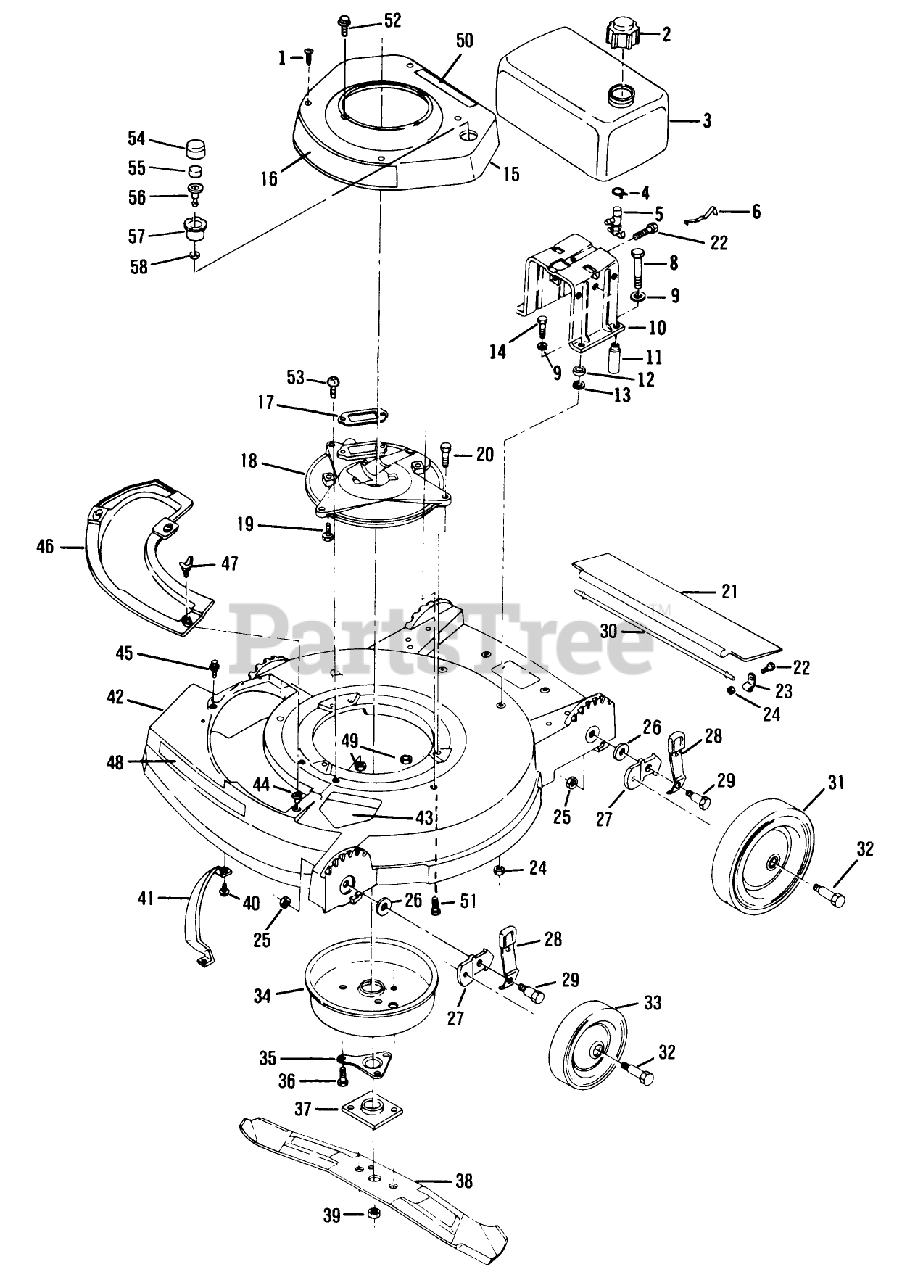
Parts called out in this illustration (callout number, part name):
1	SCREW - SELF TAPPING
2	FUEL CAP & INSERT
3	TANK - FUEL
4	CLAMP - HOSE S
5	VALVE&SCREEN SM
6	SPRING
9	WASHER
13	WASHER
14	BOLT PIONEER
18	PLATE F
19	SCREW V
20	SCREW-HH
21	T/SHIELD GEAUGA
23	CLAMP ROD KMC
24	LOCKNUT E
26	WASHER
29	BOLT
30	ROD 21" ADVANCE
31	WHEEL & TIRE
32	BOLT-SHOULDER
34	MUFFLER COVER F
35	SUPPORT F
36	SCREW
37	PLATE AND COLLAR ASM
39	NUT-BLADE
41	BAR-TOE
47	WING SCREW LAWRE
49	NUT-LOCK F
52	SCREW SEMS SM
55	FILTER S
56	BASE P'MERBULB S
57	CUP PRIMER S
